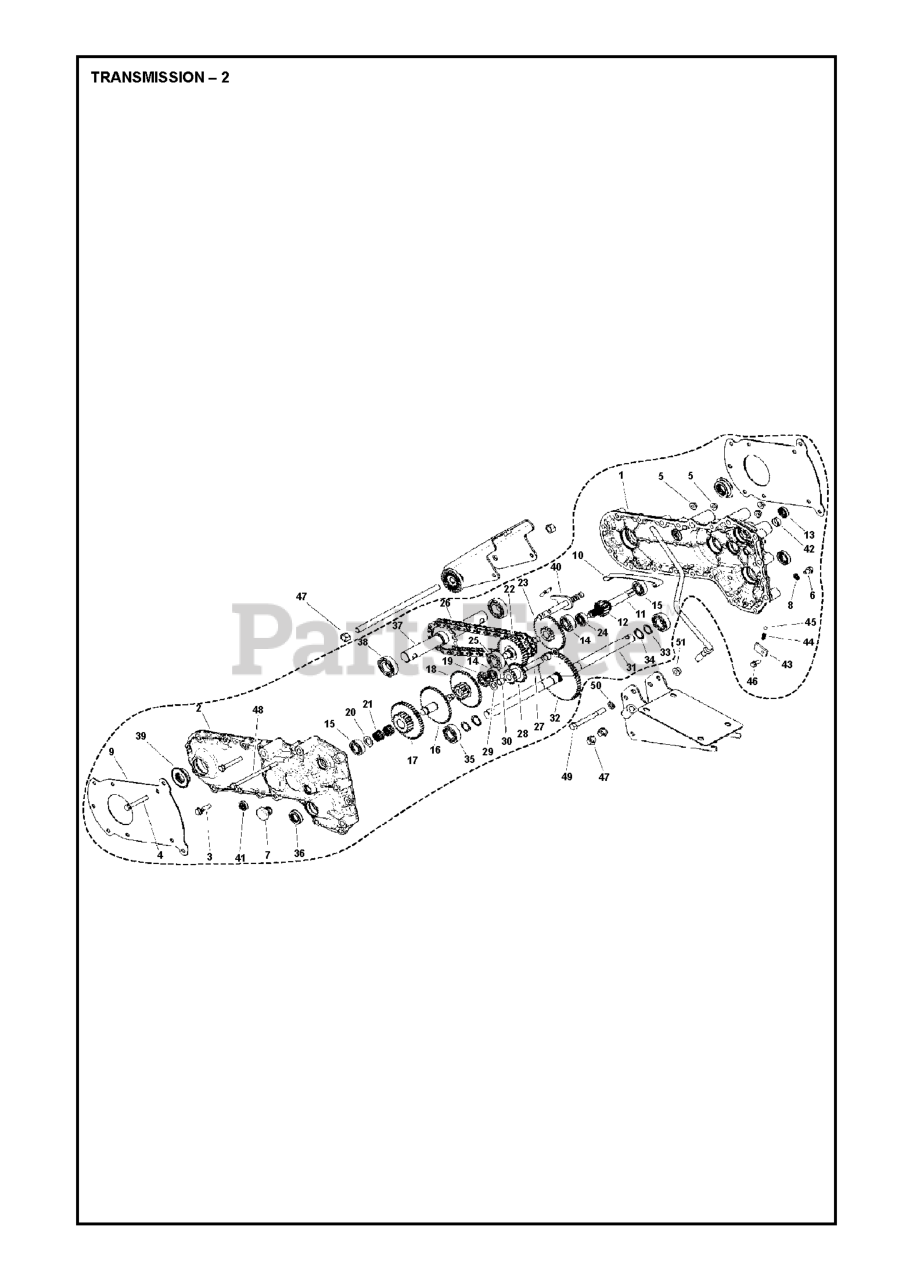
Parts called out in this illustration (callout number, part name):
8	SEAL 0002010204
34	RING 0002010227
47	NUT 0300201202
51	NUT 0300261001
